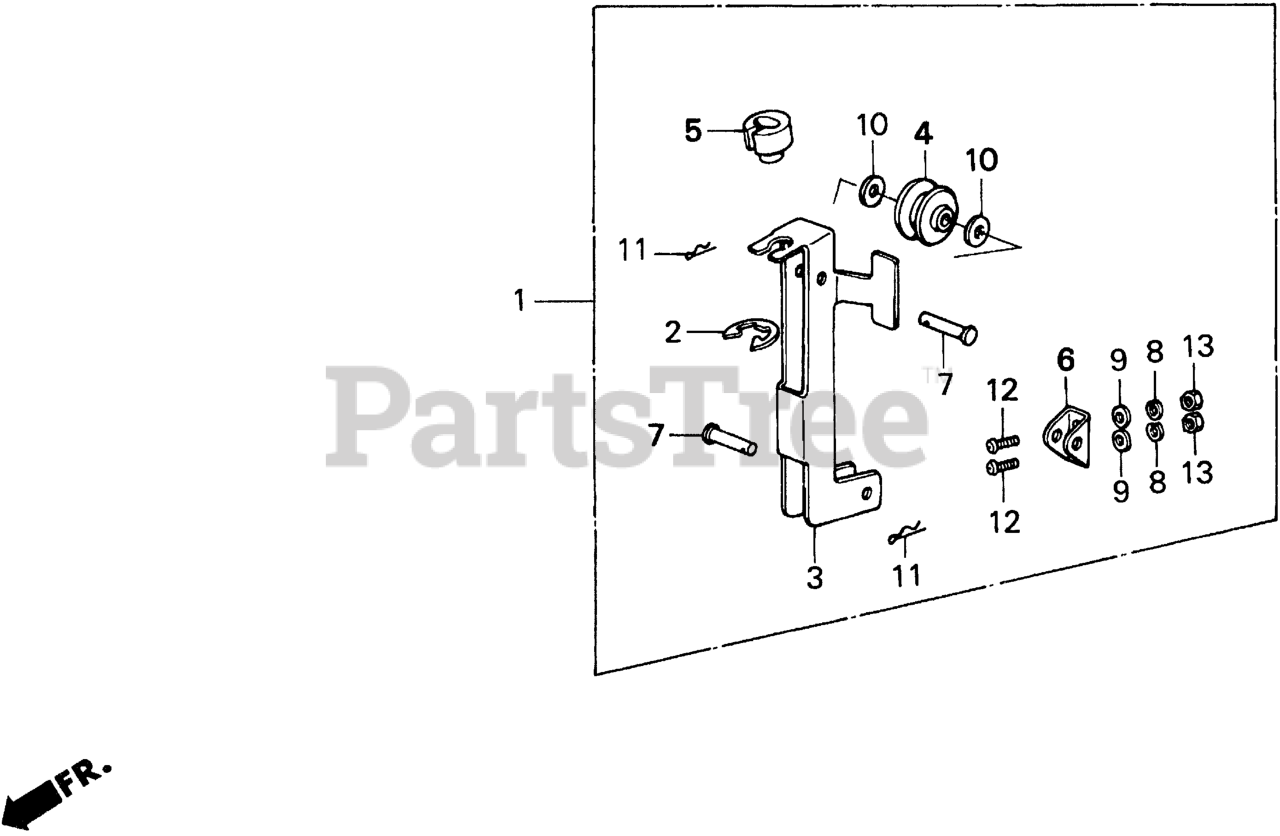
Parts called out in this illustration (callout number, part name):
1	STARTER KIT, VERTICAL (N/A: SEE COMPONENTS)
2	E-RING
3	STAY, VERTICAL STARTER
4	IDLER, VERTICAL STARTER
5	GUIDE, ROPE
6	BRACKET, VERTICAL STARTER
7	PIN, VERTICAL STARTER
8	WASHER, SPRING (6MM)
9	WASHER, PLAIN (6MM) Use from Frame SN 4800713.
10	WASHER (10MM)
11	PIN, LOCK (10MM)
12	SCREW, PAN (6X12)
13	NUT, HEX. (6MM)
